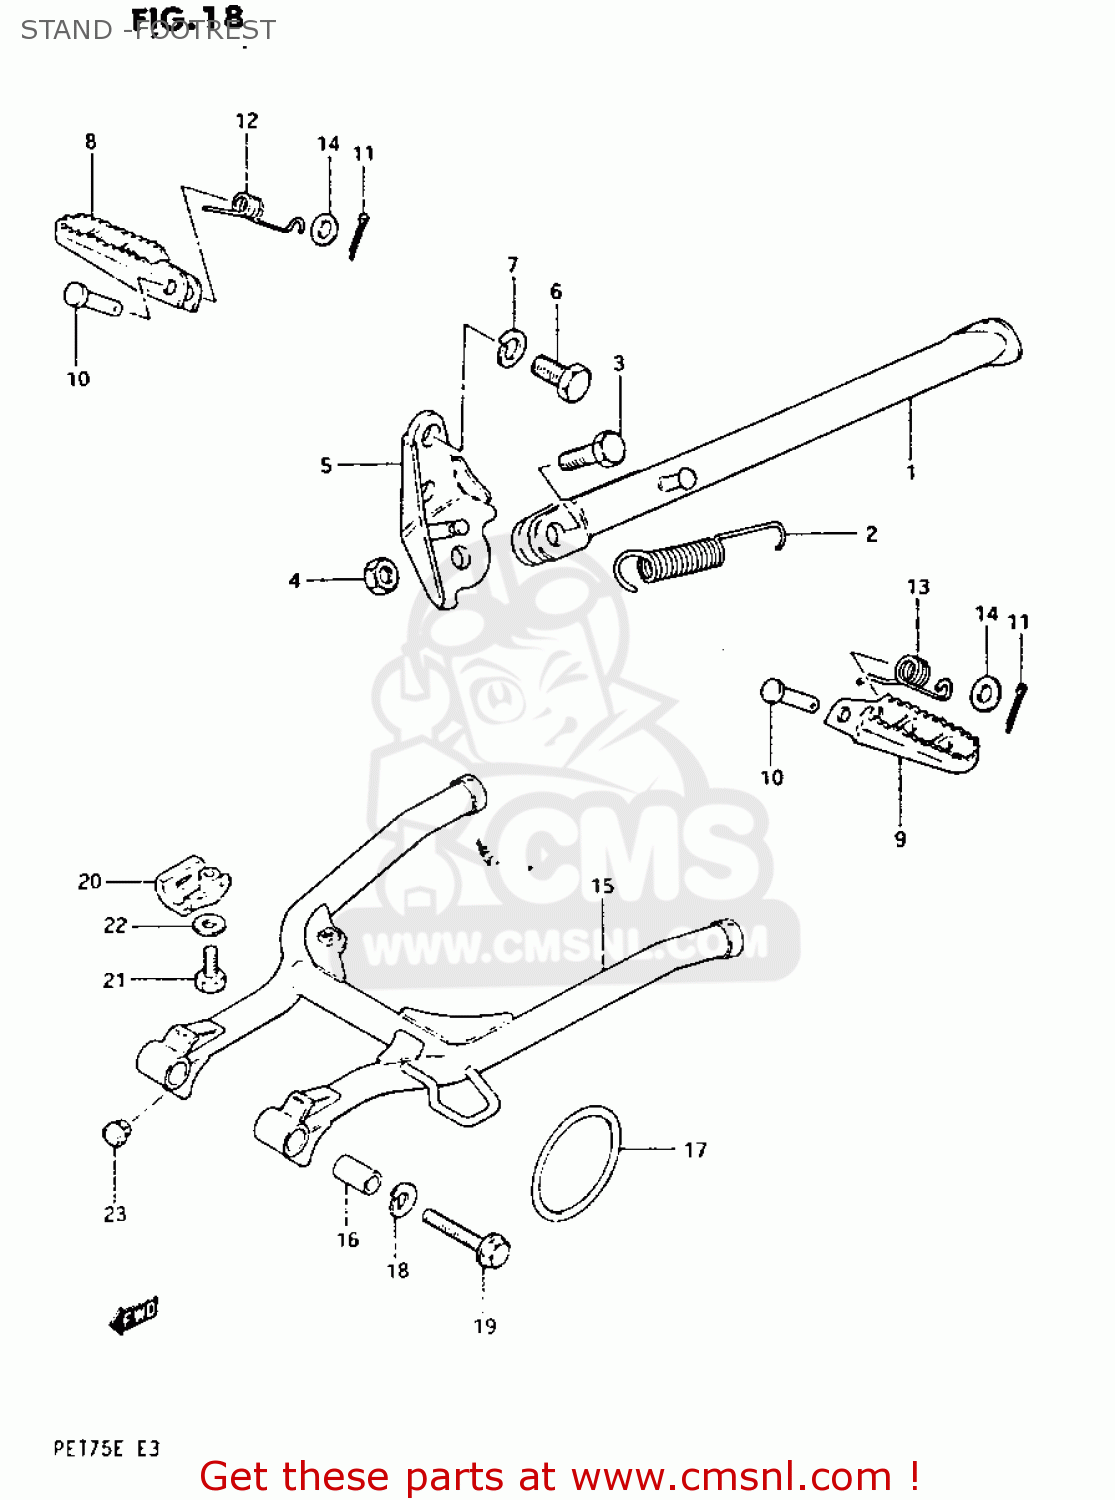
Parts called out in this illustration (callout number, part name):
1	STAND,SIDE
2	SPRING
3	BOLT(10X30)
4	NUT
5	BRACKET,SIDE STAND
6	BOLT(10X19)
7	WASHER,LOCK,10
8	FOOTREST,FR,R
9	FOOTREST,FR,L
10	PIN
11	PIN 20X20
12	SPRING
13	SPRING
14	WASHER
15	STAND,CENTER
16	SPACER(10.5X16X30)
17	O RING CTR STAND
18	WASHER,LOCK,10
19	BOLT, RH
20	PROTECTOR CTR STAND
21	BOLT
22	WASHER
23	CUSHION
